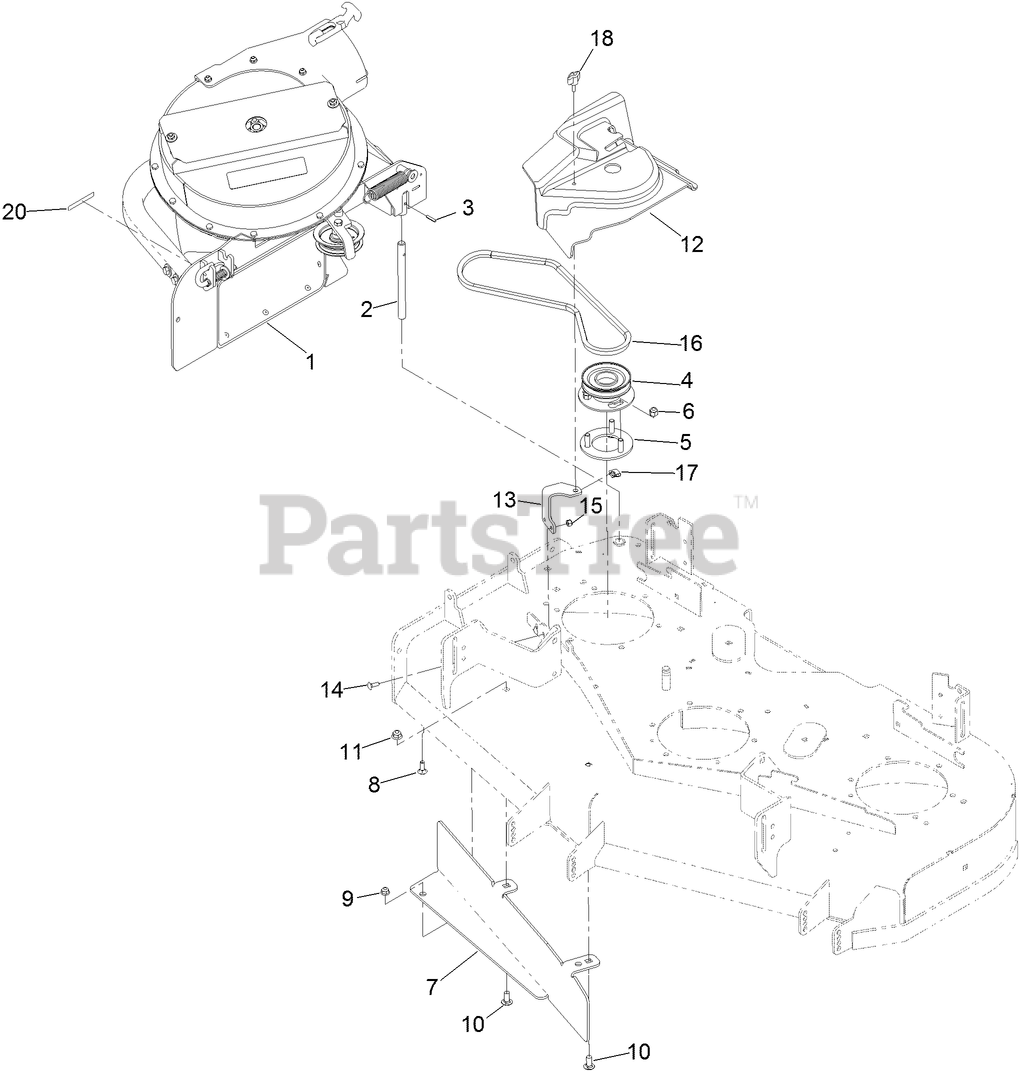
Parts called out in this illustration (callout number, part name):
1	ASM-BLOWERS DRIVE
2	SHAFT-CATCHER, GRASS
3	PIN-ROLL
4	PULLEY-BLOWER
5	PULLEY MOUNT ASM
6	NUT-LOCK, NI
7	BAFFLE-BAGGER, 48 INCH
8	SCREW-CARR
9	NUT-HF, NI
10	SCREW-CARR
11	NUT-HF, NI
12	COVER-BELT
13	BRACKET-COVER, BELT
14	BOLT-CARR
15	NUT-LOCK, NI
16	BELT-V, HI-TEMP
17	NUT-SPEED
20	DECAL-WARNING
